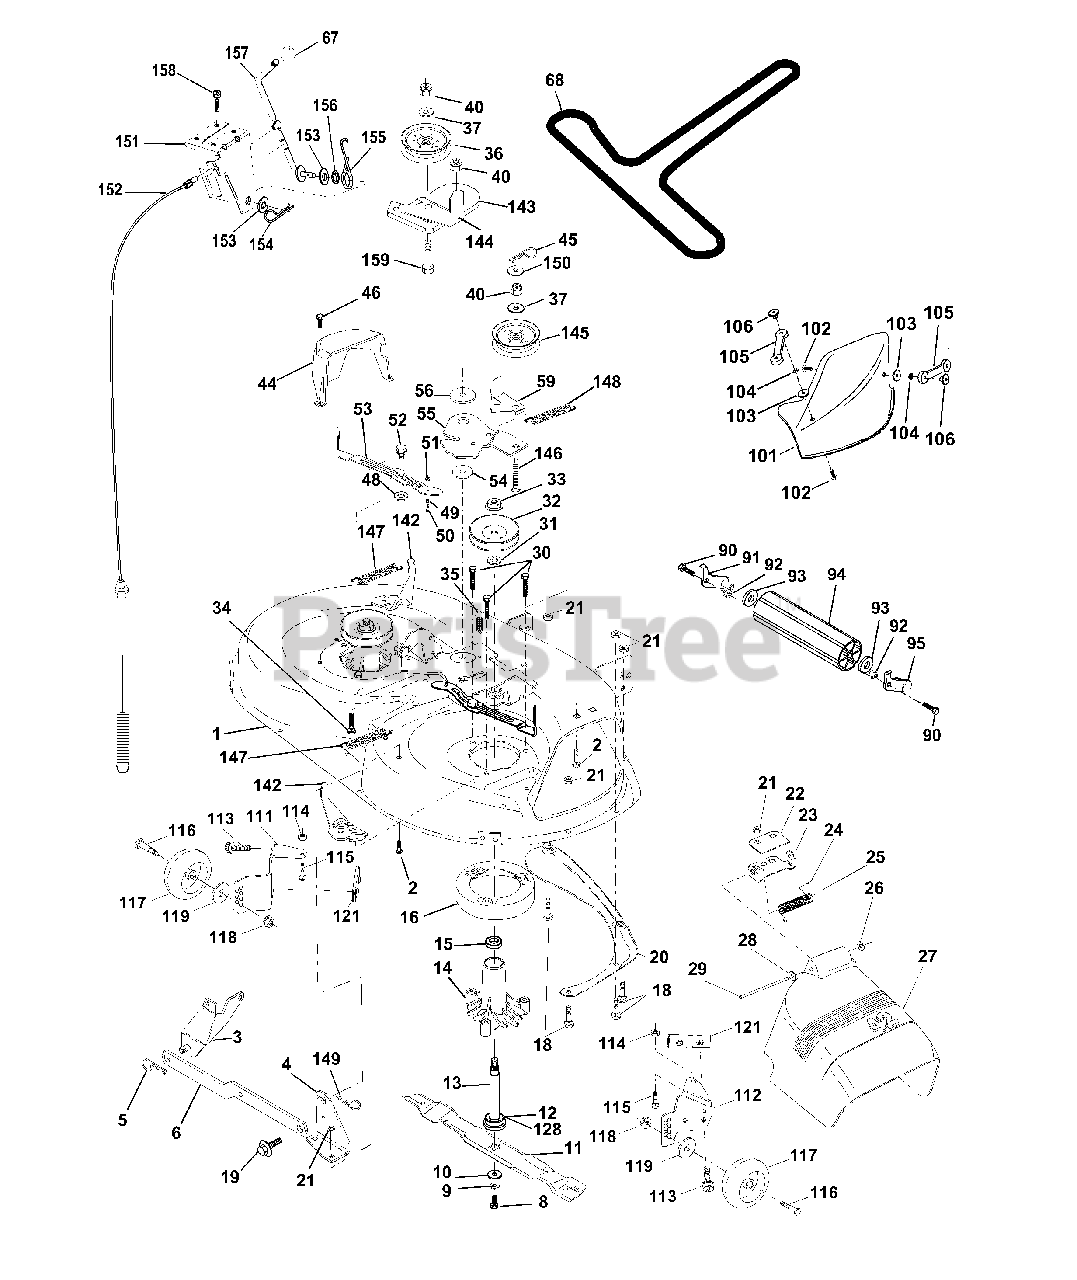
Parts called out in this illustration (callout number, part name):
1	Mower Deck Assembly, 42"
2	Bolt
3	Bracket Asm Fr. Sway Bar 3/42
4	Bracket Asm Deck 42" Sway Bar
5	Retainer Spring
6	Arm, Suspension, Rear
8	Bolt 3/8-24 x 25 Grade 8 patched
9	Washer, Lock
10	Washer,Hardened
11	Blade, Mulching 42"
11	Blade Mower 42" Hi-Lift
12	Bearing, Ball #6204
13	Shaft Assembly, Mandrel, Vented
14	Housing, Mandrel, Vented
15	Bearing, Ball, Mandrel
16	Stripper, Vented Mower Deck
18	Bolt, Carriage 5/16-18 x 5/8
19	Bolt, Shoulder
20	Baffle, Vortex
21	Nut
22	Stiffener Bracket
23	Bracket, Deflector Mower 42"
24	Cap, Sleeve 80 x 112 Blk Mower
25	Spring, Torsion, Deflector 2 52
26	Nut, Push Phos & Oil
27	Shield, Deflector 42" Blk
28	Washer 11/32 x 5/8 x 16 Gauge
29	Rod, Hinge 42" 6 75 W/G
30	Screw Thdrol Washer Head
31	Washer, Spacer Mower Vented
32	Pulley, Mandrel
33	Nut, Toplock 9/16
34	Bolt
35	Fastener, Christmas Tree
36	Pulley, Idler, Flat
37	Washer 13/32 x 13/16 x 16 Gauge
40	Nut
44	Guard, Mandrel, LH
45	Retainer
46	Screw, Thdrol 1/4-20 x 5/8 T
48	Washer,Hardened
49	Roller Assembly, Cam Follower
50	Bolt, Shoulder #10-24 Grade 5
51	Locknut
52	Bolt, Shoulder 5/16-18 UNC
53	Arm Assembly, Pad, Brake
54	Washer,Hardened
55	Arm, Idler
56	Spacer, Retainer
59	Guard TUV Idler
67	Knob
68	V-Belt, 42" Mower
90	Bolt Fin Hex 3/8-16 Unc x 1
91	Bracket Asm. Noseroller LH
92	Nut, Lock, Hex W/Ins 3/8-16 UNC
93	Washer 17/32 x 7/8 x 16 Ga.
94	Roller, Nose
95	Bracket Asm. Noseroller RH
101	Mulcher Cover
102	Screw
103	Washer, Flat
104	Washer, Lock
105	Latch Assembly
106	Nut, Weld
111	Bracket, Gauge, Wheel LH
112	Bracket, Gauge, Wheel RH
113	Screw 5/16 - 18 x 3/4
114	Nut, Keps 5/16 - 18 UNC
115	Bolt, Carriage 5/16-18 x 1/2
116	Bolt, Shoulder
117	Wheel, Gauge
118	Nut Centerlock 3/8-16
119	Washer 3/8 x 7/8 x 14 Ga.
121	Bracket, Extruded
128	Washer, Felt
142	Arm Spring Brake Mower
143	Bracket Arm Idler 42"
144	Keeper Belt 42" Clutch Cable
145	Pulley Idler Flat
146	Bolt Carriage Idler
147	Spring Extension
148	Spring Return Idler
149	Retainer Spring Yellow
150	Washer 9/32 x 3/4 x 16 Ga.
151	Bracket Clutch Cable
152	Clutch Cable 42"
153	Washer Flat 3/8" Type B
154	Spring Retainer
155	Spring Retention LVR CLTCH CAB
156	Spacer Clutch Cable
157	Rod Clutch Cable 3/8"
158	Screw Hex Thd Cut 1/4-20 x 5/8
159	Bolt Rdhd Sqn 3/8-16 UNC x 1-3/4
